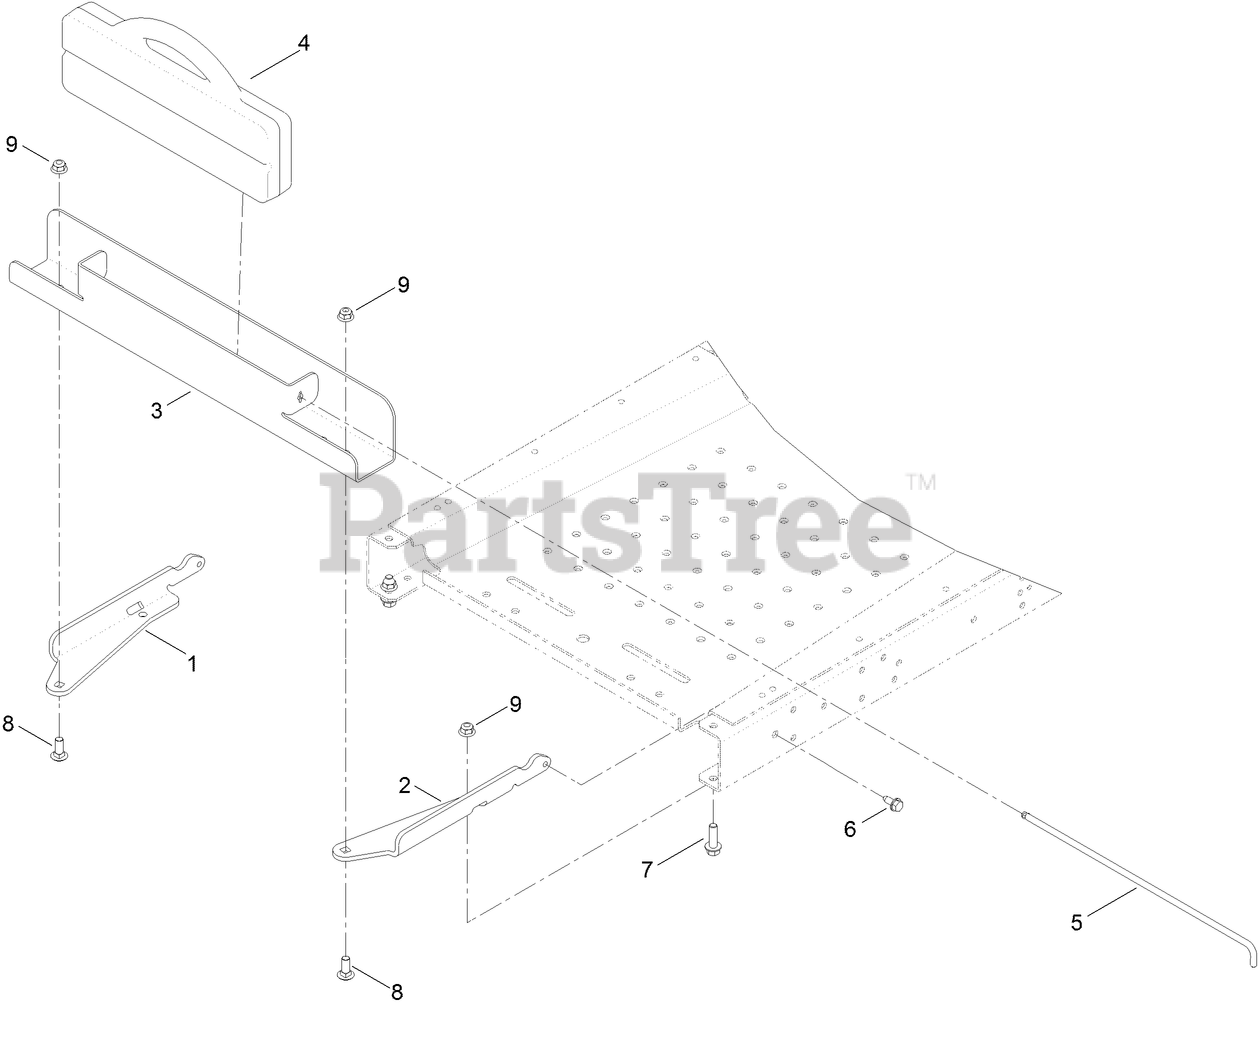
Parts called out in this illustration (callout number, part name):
1	BRACKET-WEIGHT, RH
2	BRACKET-WEIGHT, LH
3	CHANNEL-WEIGHT, BAGGER
4	WEIGHT-35 POUND
5	PIN-WEIGHT
6	SCREW-HWHTF
7	SCREW-HHF
8	BOLT-CARR
9	NUT-HF, NI
